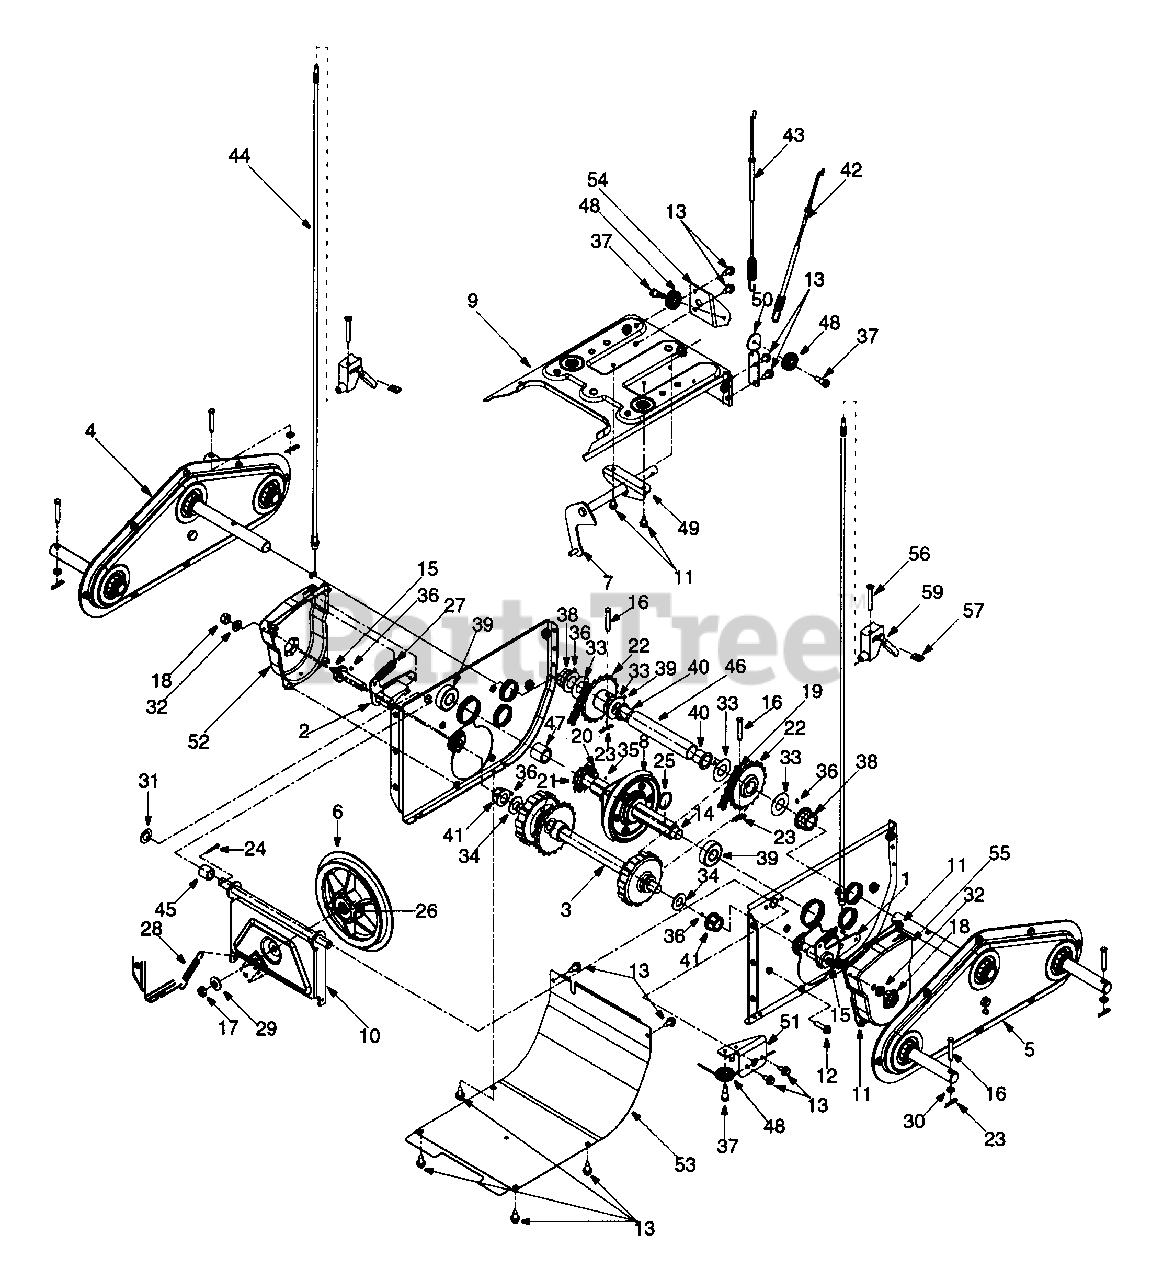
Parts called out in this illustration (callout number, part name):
1	Dogg Assembly: RH
2	Dogg Assembly: LH
3	Shift Assembly: Steerable Drive
4	Chain Case Assembly: RH
5	Chain Case Assembly: LH
6	Friction Wheel Disc Assy.
8	Wheel Assembly, Friction
9	Transmission Frame Assembly
12	Hex Washer Hd. TT Screw 1/4-20 x 1.0"
13	Hex Washer Hd. TT Screw 1/4-20 x .625"
15	Actuator Shaft
17	Jam Nut 3/8-24 Gr.8
18	Hex Nut: 3/8-16
21	Sprocket: 19T
26	Adhesive: Loctite(R)
27	Extension Spring
28	Extension Spring
35	Lubricant
36	Grease
37	Shoulder Screw
38	Hex Flange Bearing
39	Ball Bearing
40	Flange Bushing
41	Hex Flange Bearing
42	Auger Clutch Cable
43	Drive Clutch Cable
44	Steering Cable
46	Support Tube: Axle
48	Roller Cable
53	Frame Cover
54	Roller Bracket: Drive Cable
55	Retaining Shaft LH: Actuator Drive
56	Oval C-Sunk Machine Screw
59	Turn Trigger
